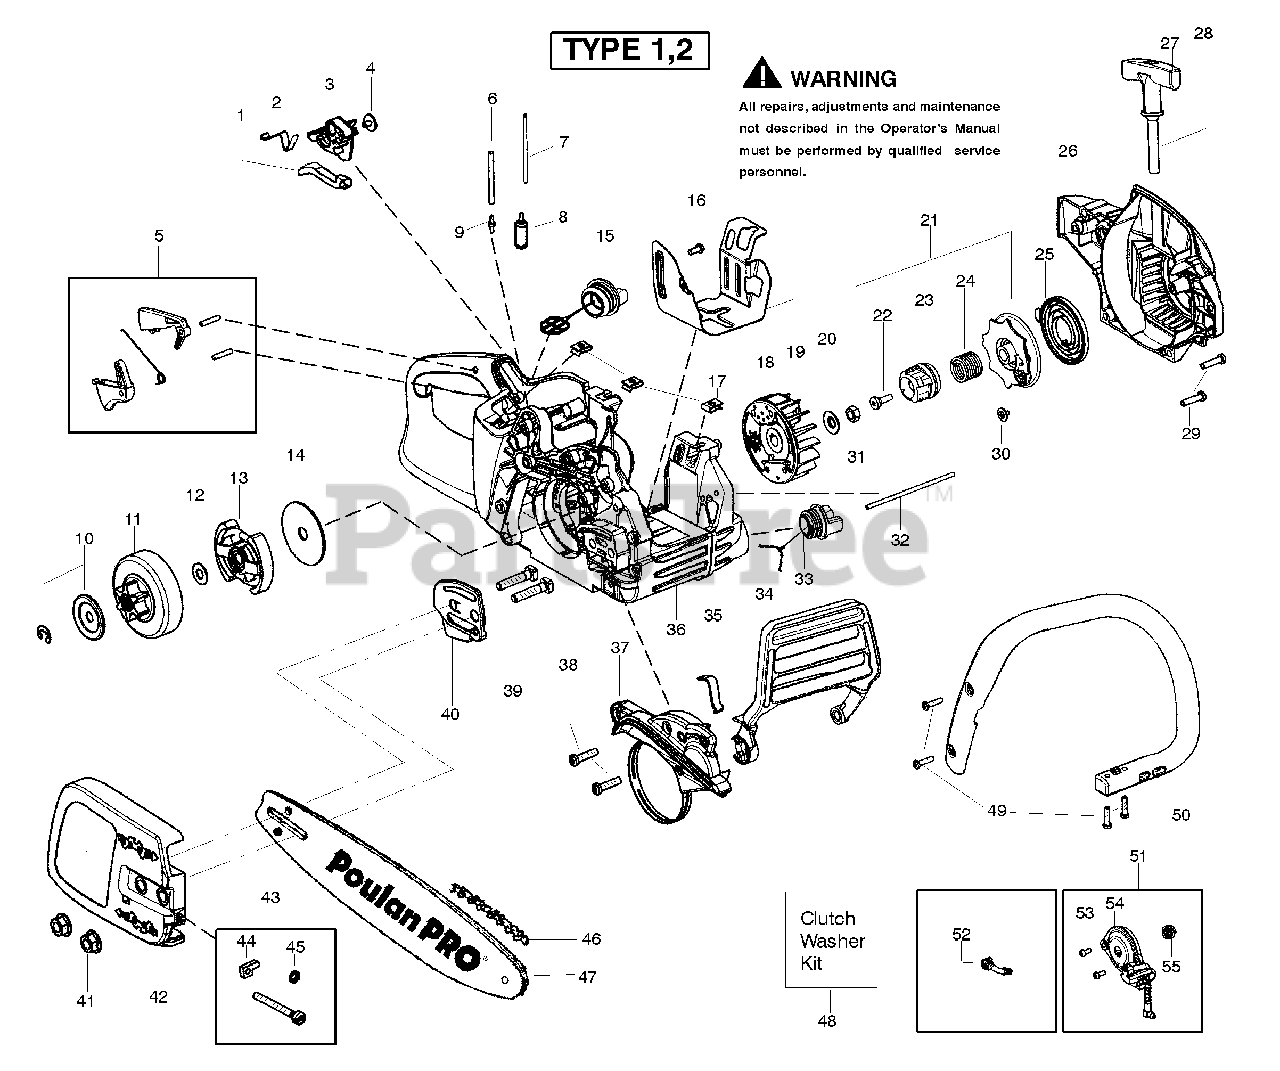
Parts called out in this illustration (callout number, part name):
1	Knob-Choke
2	Spring-Ign. Switch
3	Lever-Ign. Switch
5	Kit-Trigger/Lockout
6	Kit-Fuel Line
7	Kit-Fuel Line
8	Assy-Fuel Pick Up
9	Fitting-Fuel line
10	Kit-Clutch Washer
11	Assy-Clutch Drum 3/8'
12	Kit-Clutch Washer
13	Assy-Clutch
14	Washer-Large Clutch
15	Assy-Fuel Cap w/ret
17	Nut-'U' type speed
18	Assy-Flywheel
19	Shield-Heat
20	Washer-Flywheel
21	Kit-EPS Starter Pulley
22	Screw-Shoulder
24	Spring-EPS
25	Spring-Starter
26	Housing-Fan
27	Handle-Starter
28	Kit-Rope
31	Nut-Flywheel
32	Assy-Oil Vent
33	Assy-Oil Cap w/ret.
34	Handguard
35	Spring-Handguard
36	Assy-Chassis
37	Kit-Chainbrake
39	Bolt-Bar
40	Plate-Bar
42	Assy-Clutch Cover
43	Kit-Bar Adjust
44	Pin-Bar Adjust
45	Retainer-Bar Adjust
46	Accy-18' Chain
47	Accy-18' Bar
48	Kit-Clutch Washer
50	Handle-Front
51	Kit-Oil Pump
52	Assy-Oil Pick Up
54	Assy-Oil Pump
55	Gear-Worm
